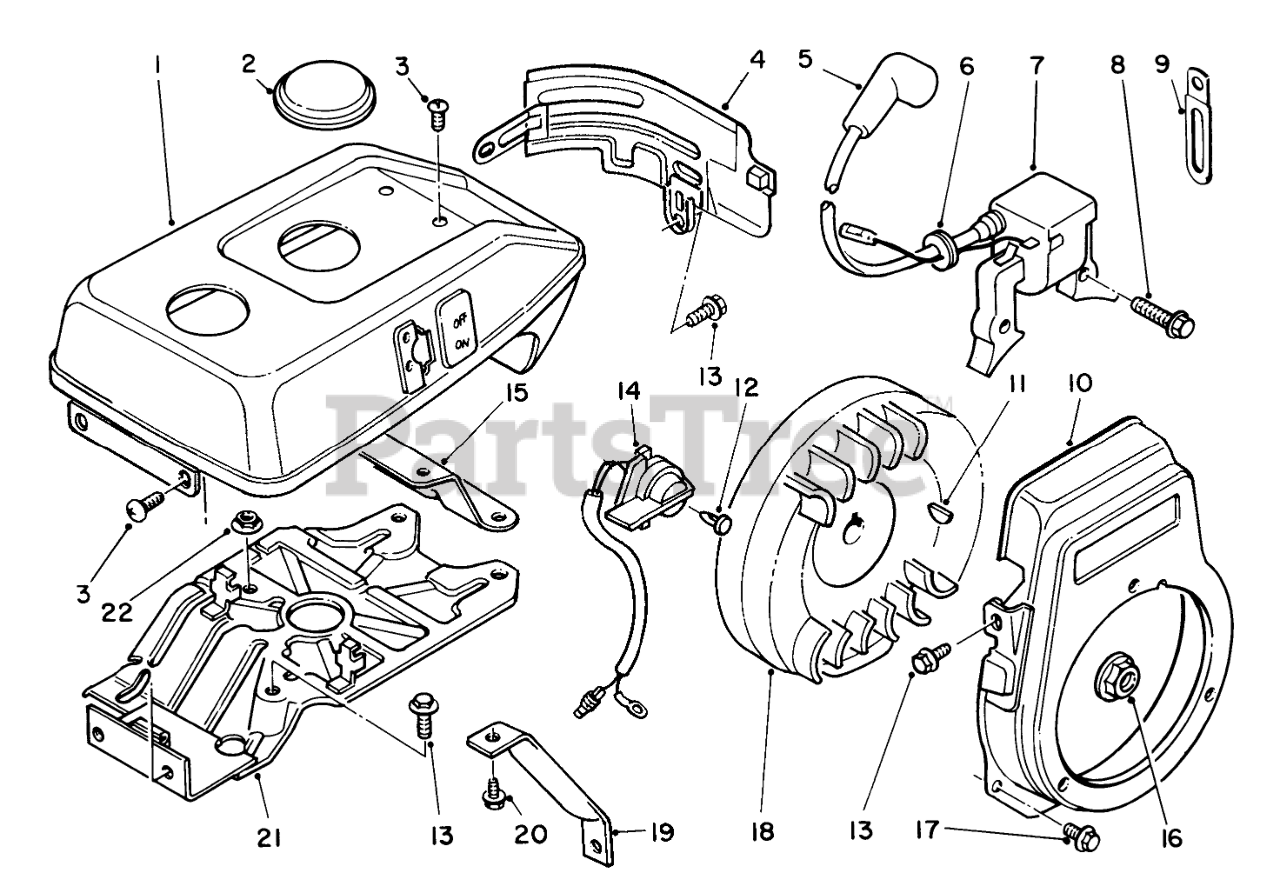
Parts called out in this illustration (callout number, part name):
1	Cover-Engine
3	Screw-Round Phillips Hd.
4	Cowling-Side
5	CAP-SPARKPLUG
6	Grommet
7	Magneto Assembly (Incl.Ref. #5 & 6)
9	CLAMP
10	Cover-Cooling Fan
14	Switch-Engine
15	Bracket-Engine Cover
18	Rotor
19	Support-Fuel Tank
20	SCREW-HHF
21	Cowling-Upper
